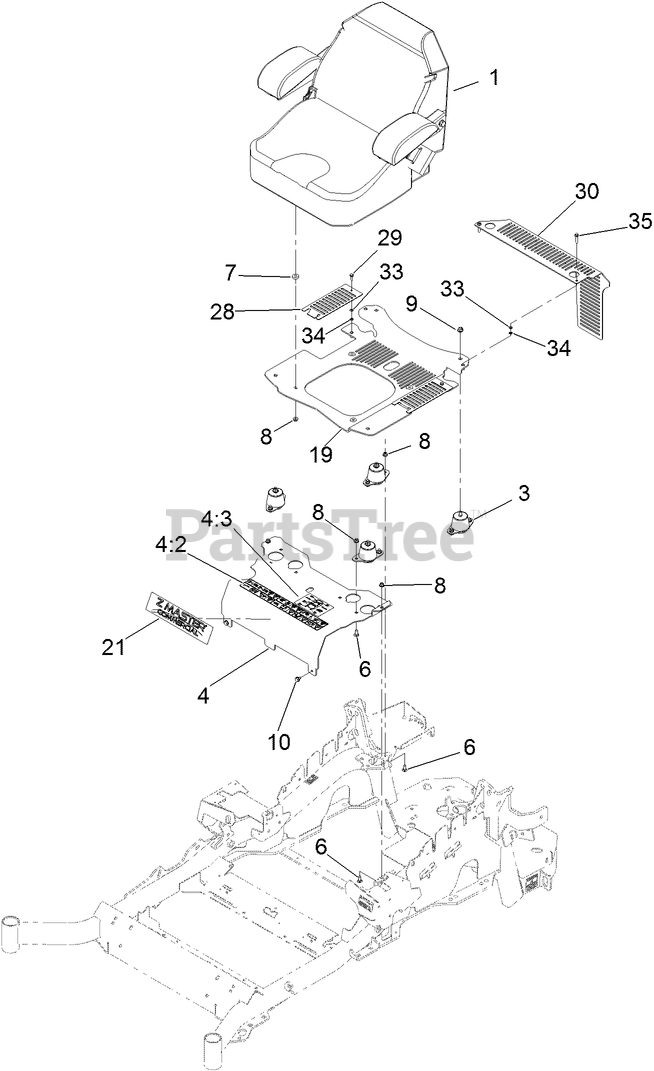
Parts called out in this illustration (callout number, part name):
1	SEAT-STANDARD
3	ISOLATOR-SEAT
4	MOUNT-SEAT
4:2	DECAL-CONSOLE
4:3	DECAL-SERVICE AID
6	SCREW-CARR
7	SPACER-PIN, MOUNTING
8	NUT-HF, NI
9	NUT-HF, NI
10	SCREW
19	SEAT BASE ASM
29	SCREW-HWH
30	GUARD-CE
33	WASHER-FLAT
34	NUT-RETAINER
35	SCREW-HHF
